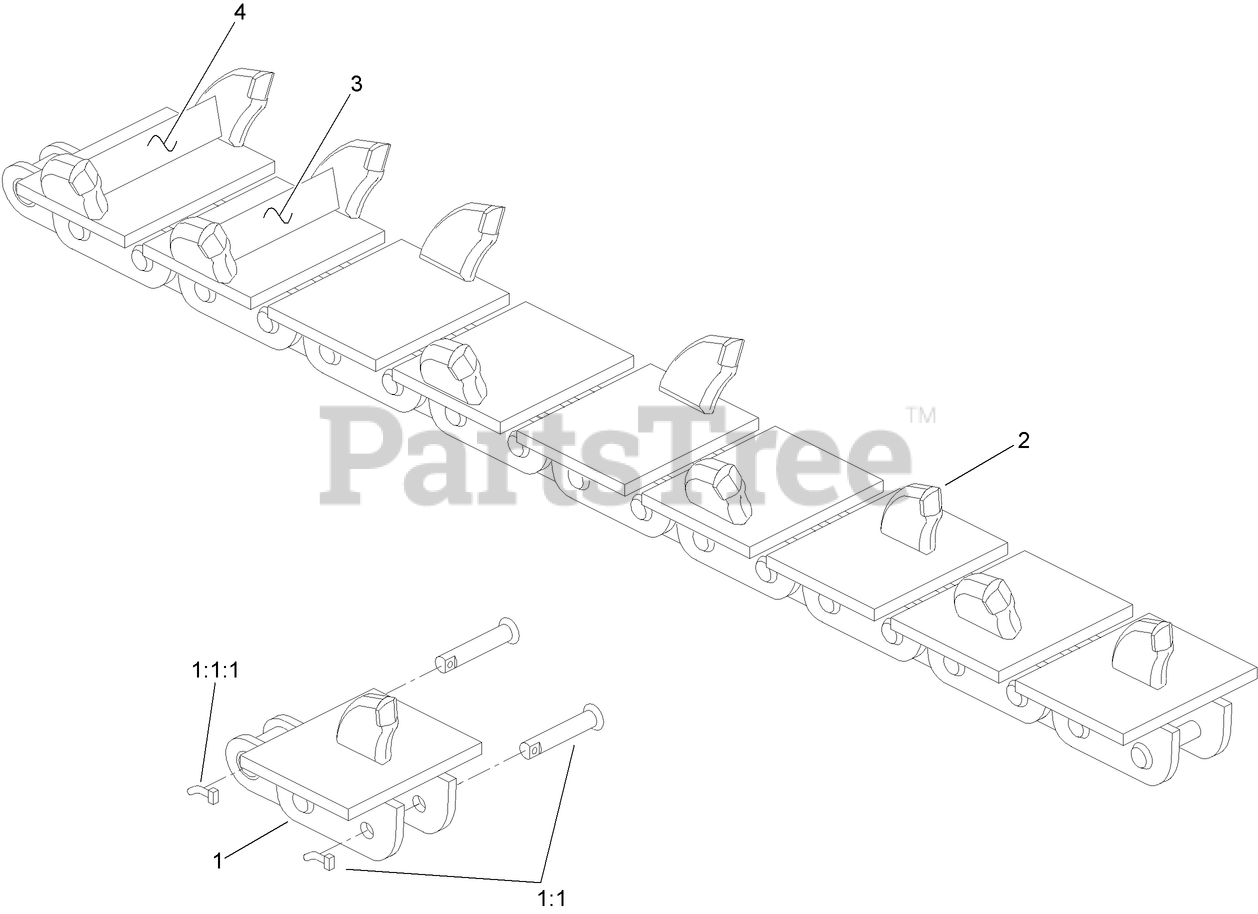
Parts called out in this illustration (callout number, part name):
1	CHAIN REPAIR LINK ASM
1:1	NOTCHED PIN AND KEEPER ASM
1:1:1	PIN-KEEPER
2	TOOTH-TERMINATOR, WELD-ON
3	DRAG-DIRT, WELD-ON (4 INCH)
4	DRAG-DIRT, WELD-ON (6 INCH)
